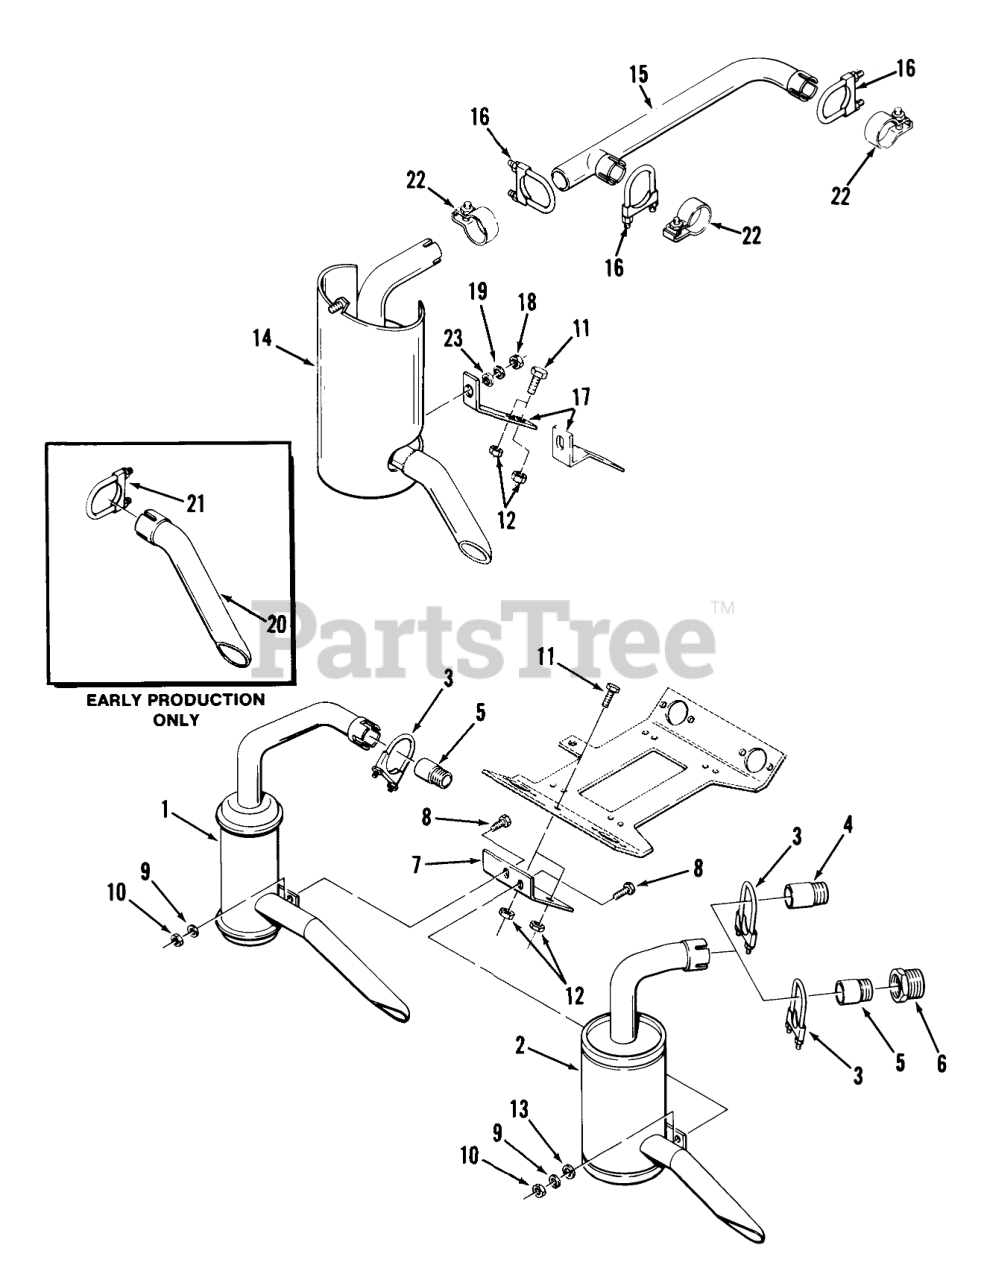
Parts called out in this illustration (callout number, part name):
1	ASSY-MUFFLER
2	MUFFLER ASSEMBLY
3	ASSY-MUFFLER CLAMP
4	NIPPLE
5	NIPPLE- 1X2 SPECIAL
6	REDUCER 1 1/4-1
7	BRACKET-MUFFLER MTG
8	H H C S
9	Washer
10	Nut 1/4 C-85, C-105, C-125, C-145, C-165 Only
11	Bolt
12	Nut
14	Muffler C-175 Twin Only
15	MANIFOLD-EXHAUST
16	CLAMP-1 1/2
17	Muffler Mounting Bracket C-175 Twin Only
17	BRACKET-MUFFLER
18	Nut
19	LOCKWASHER
20	Muffler Extension C-175 Twin Only
21	ASSY-MUFFLER CLAMP
22	CLAMP-MUFFLER
23	Washer
